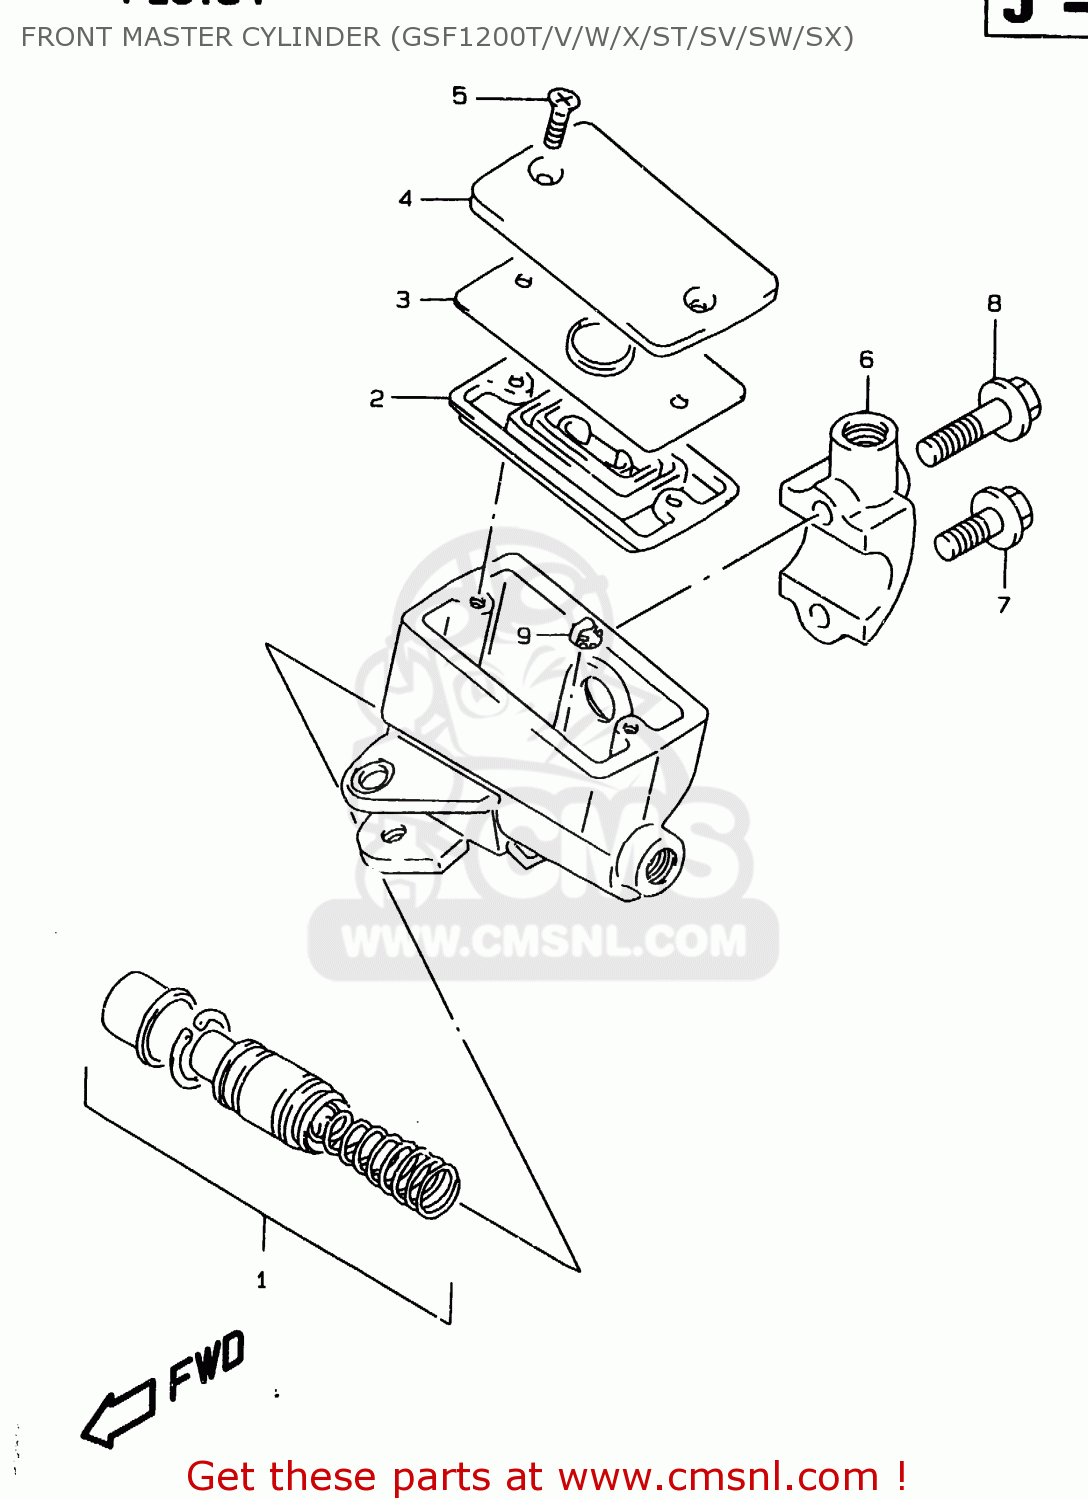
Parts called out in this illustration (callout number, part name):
1	PISTON & CUP SET
2	3
3	PLATE,DIAPHRAGM
4	CAP
5	SCREW
6	HOLDER
7	BOLT(6X25)
8	BOLT(6X38)
9	PROTECTOR
